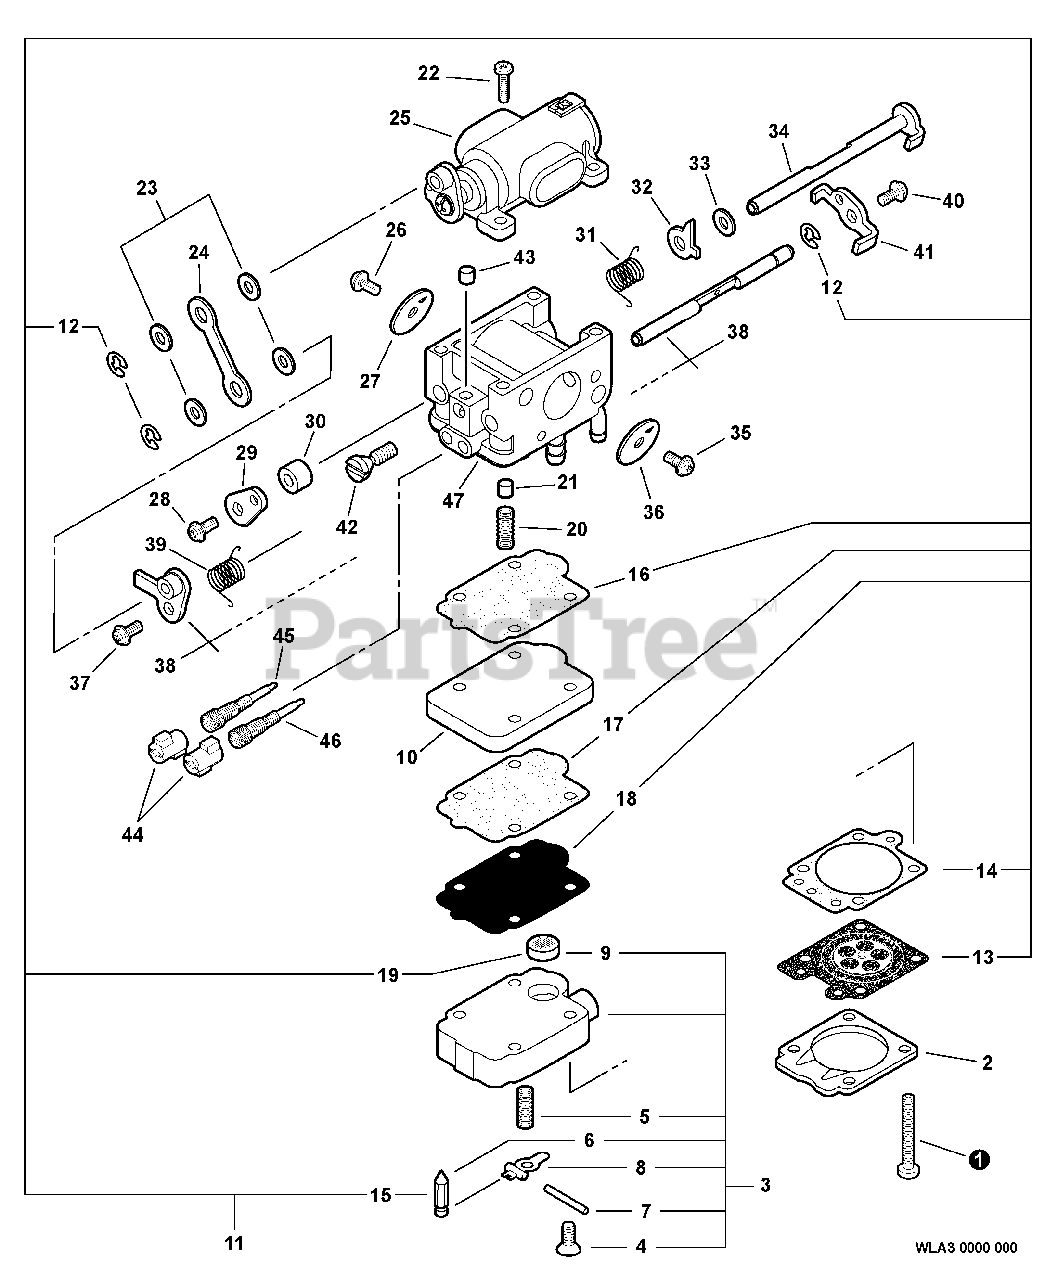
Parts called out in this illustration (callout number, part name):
2	COVER, METERING
3	PUMP BODY ASSY
4	SCREW, METERING LEVER PIN
5	SPRING, METERING LEVER
6	VALVE, INLET NEEDLE
7	PIN, METERING LEVER
8	LEVER, METERING
9	STRAINER
10	PLATE, PASSAGE
11	REPAIR KIT
12	RING, RETAINING
13	DIAPHRAGM, METERING
14	GASKET, METERING
15	VALVE, INLET NEEDLE
16	GASKET, PASSAGE
17	GASKET, PUMP
18	DIAPHRAGM, PUMP
19	STRAINER
21	PISTON ASSY
25	AIR VALVE ASSY
27	VALVE, CHOKE
29	LEVER, CHOKE
32	LEVER, CHOKE
34	SHAFT, CHOKE
36	VALVE, THROTTLE
38	THROTTLE SHAFT ASSY
41	LEVER, THROTTLE
42	SCREW, IDLE ADJUST
44	CAP, LIMITER
45	NEEDLE - HIGH SPEED
46	NEEDLE - LOW SPEED
47	BODY, CARBURETOR
